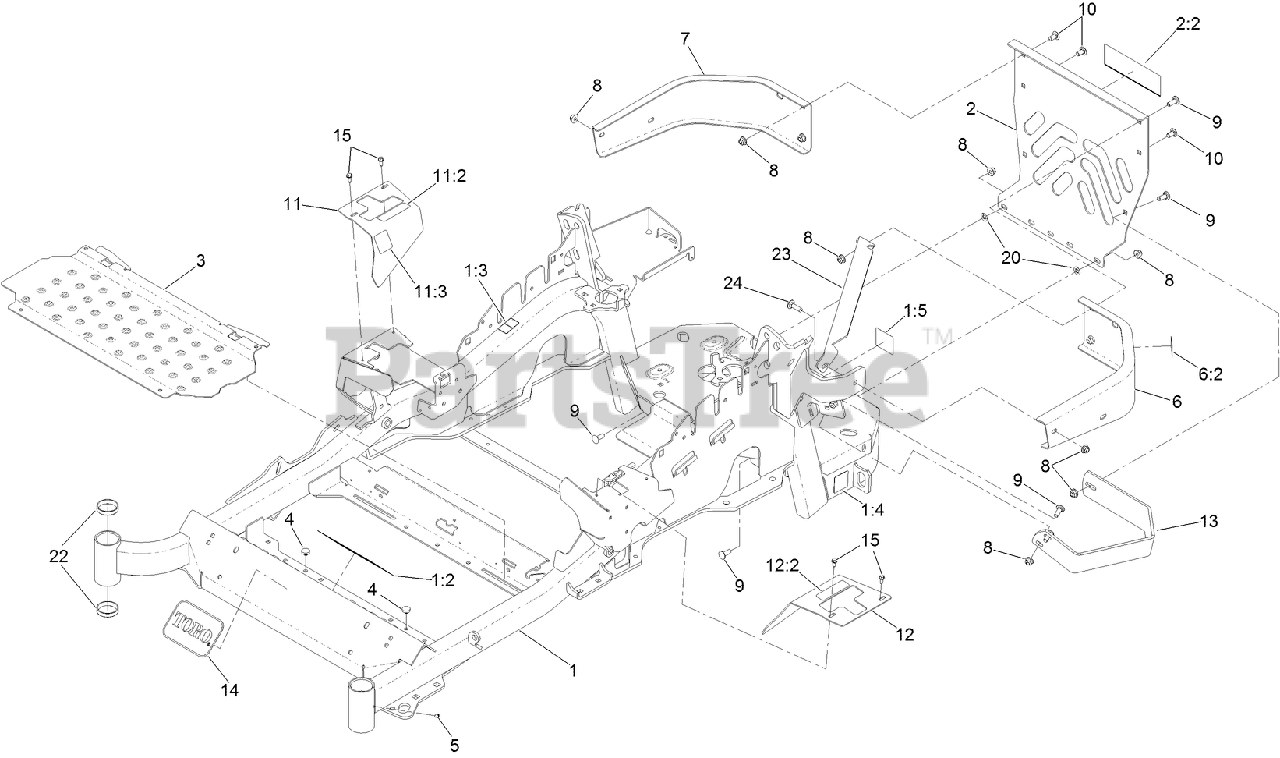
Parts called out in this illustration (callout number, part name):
1	MAINFRAME ASM
1:2	DECAL-DANGER
1:3	DECAL-WARNING
1:4	DECAL-HAZARD, PINCHED FINGER
1:5	DECAL-ARRESTOR, SPARK
2	REAR GUARD ASM
2:2	DECAL
3	FLOORPAN
4	BUMPER
6	LH BUMPER ASM
6:2	DECAL-WARNING
7	BUMPER-RH
8	NUT-HF, NI
9	SCREW-CARR
10	SCREW-CARR
11	RH MOTION CONTROL COVER ASM
11:2	DECAL-CONTROL, MOTION
11:3	DECAL-PARK BRAKE, CE
12	LH MOTION CONTROL COVER ASM
12:2	DECAL-CONTROL, MOTION
13	GUARD-MUFFLER
14	DECAL
15	SCREW-HWH
20	NUT-PUSH
22	CUP-BEARING
24	BOLT-CARR
